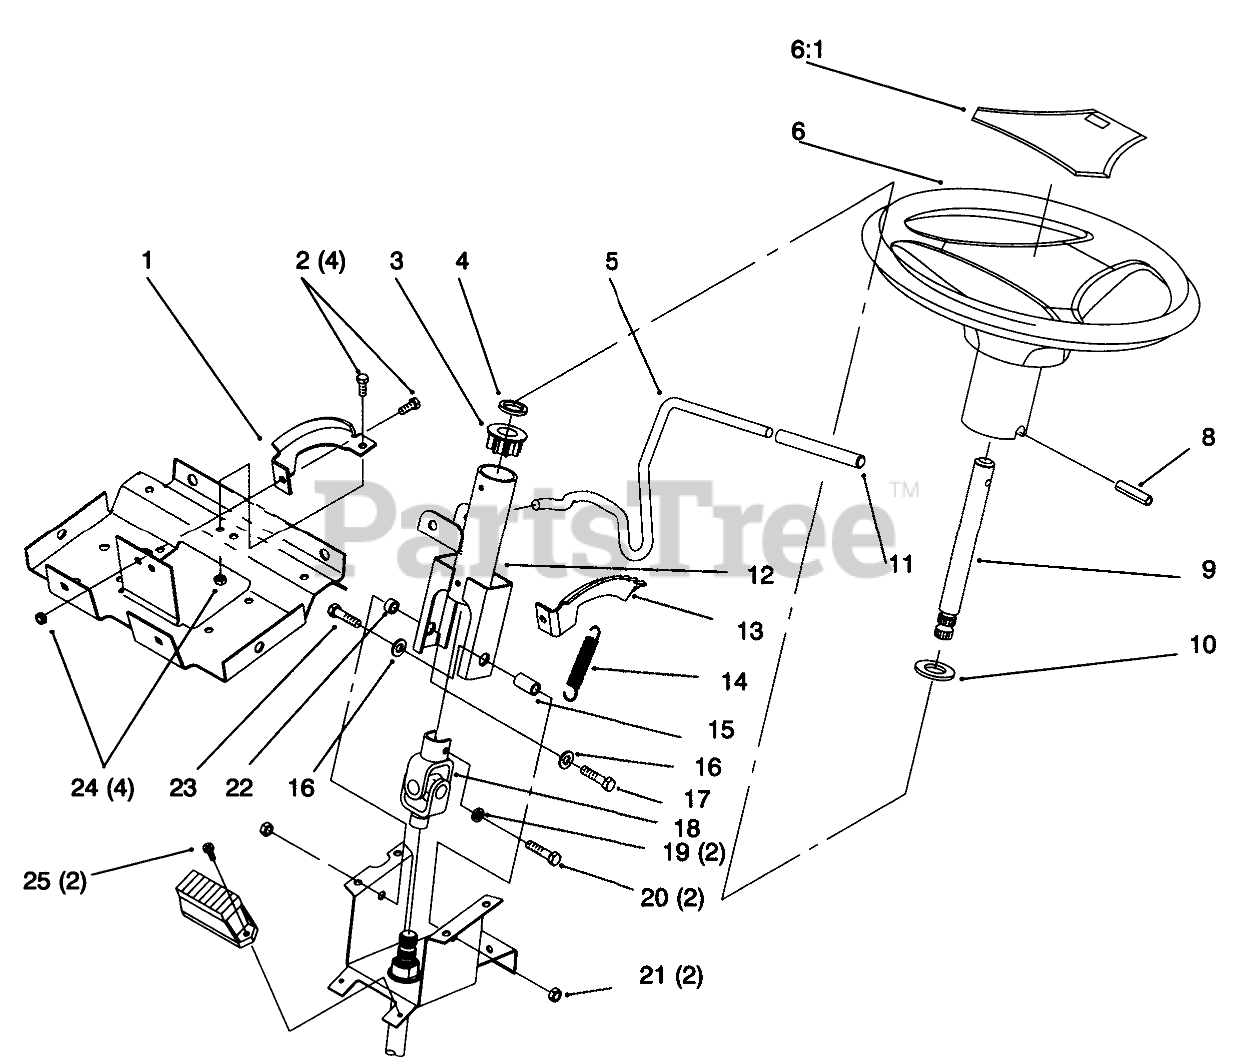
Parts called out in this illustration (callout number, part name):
1	BRACKET-SUPPORT, COLUMN
2	SCREW-HH
3	BUSHING-STEERING, UPPER
4	WASHER-BOWED
5	LEVER-TILT
6	Steering Wheel (Only On: 72042, 72043, 72062)
6	Steering Wheel (Only On: 72063, 72103)
6:1	Cover-Steering Wheel (Only On: 72063, 72103)
6:2	Cover-Steering Wheel (Only On: 72043, 72062)
8	PIN-ROLL
9	SHORT UPPER STRG SHAFT
10	WASHER-FLAT
11	CAP-ROD, TILT
12	COLUMN ASM
13	BRACKET-DETENT
14	SPRING-EXTENSION
15	SPACER-YOKE
16	WASHER-PLAIN
17	SCREW-HH
18	U-JOINT, STEERING
19	WASHER-LOCK
20	SCREW-CAP, HH
21	NUT-LOCK, NI
22	SPACER-YOKE, RIGHT
23	SCREW-HH
24	NUT-HEX
25	SCREW-PPHTF
